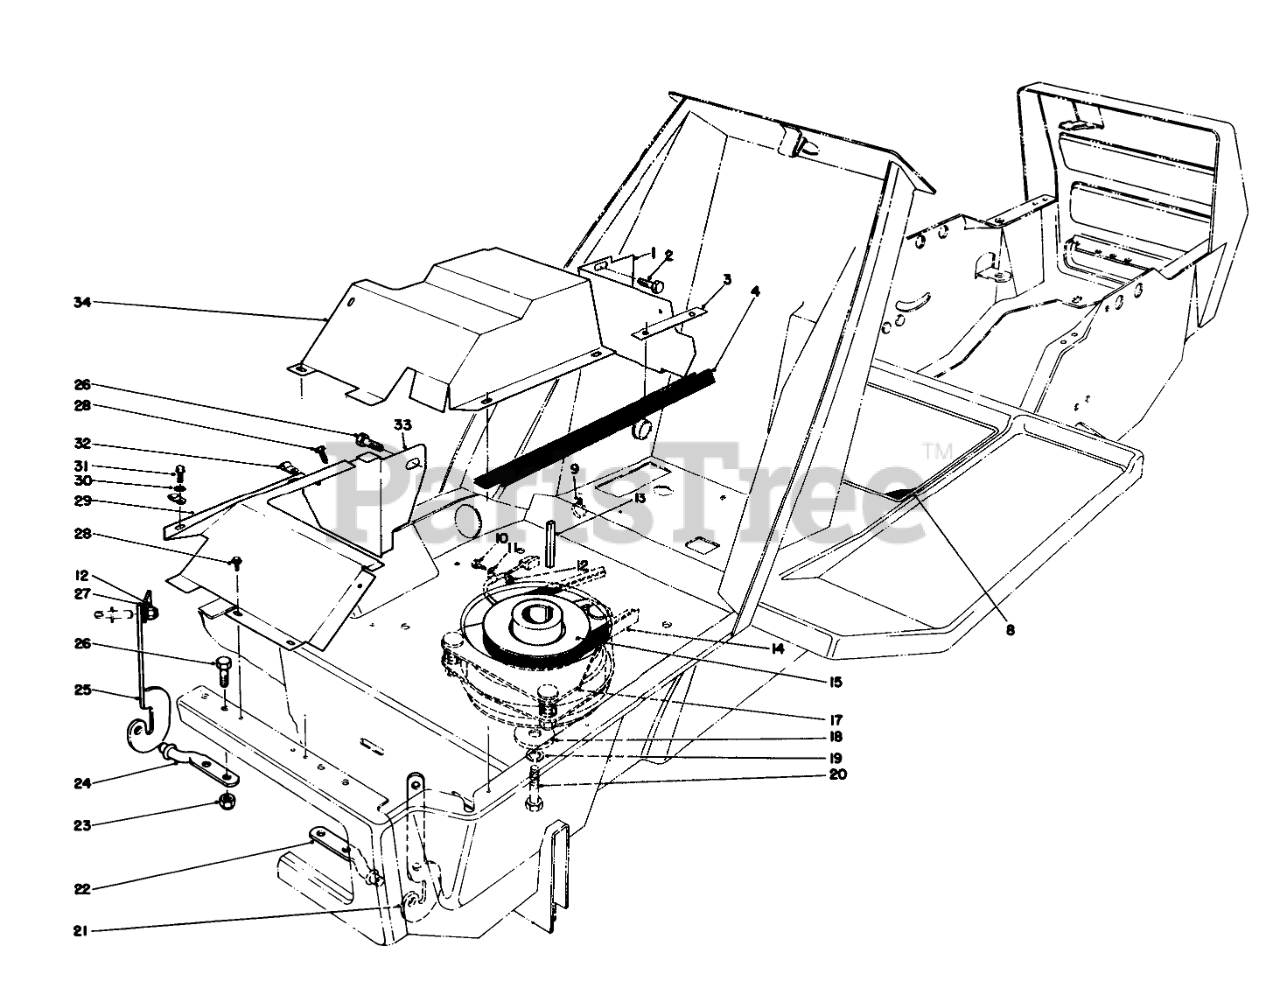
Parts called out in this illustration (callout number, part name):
1	L/H EXH SHIELD SUPT B
2	SCREW-HH
3	HOOD SEAL STRAP-PLT
4	LOWER HOOD SEAL
8	OPERATION DECAL
9	TIE-MOUNT, PUSH
10	SCREW-HH
11	CLAMP
12	NUT-LOCK, NI
13	KEY-SQUARE
14	V BELT
15	Pulley
17	Clutch Assembly-Deck
18	WASHER-CLUTCH
19	WASHER-LOCK
20	SCREW-HH
21	L.H. HINGE BRACKET
22	LH HOOD HINGE PIN
23	NUT-LOCK, CONE
24	RH HOOD HINGE PIN
25	RH HINGE BRKT
26	SCREW-HH
27	SCREEN SUPT BRKT
28	SCREW-HWHTF
29	R/H HEAT SHIELD B
30	WASHER-FLAT
31	SCREW
32	CABLE CLAMP
33	R/H HEAT SHLD SUPT B
34	L/H HEAT SHIELD WA B
